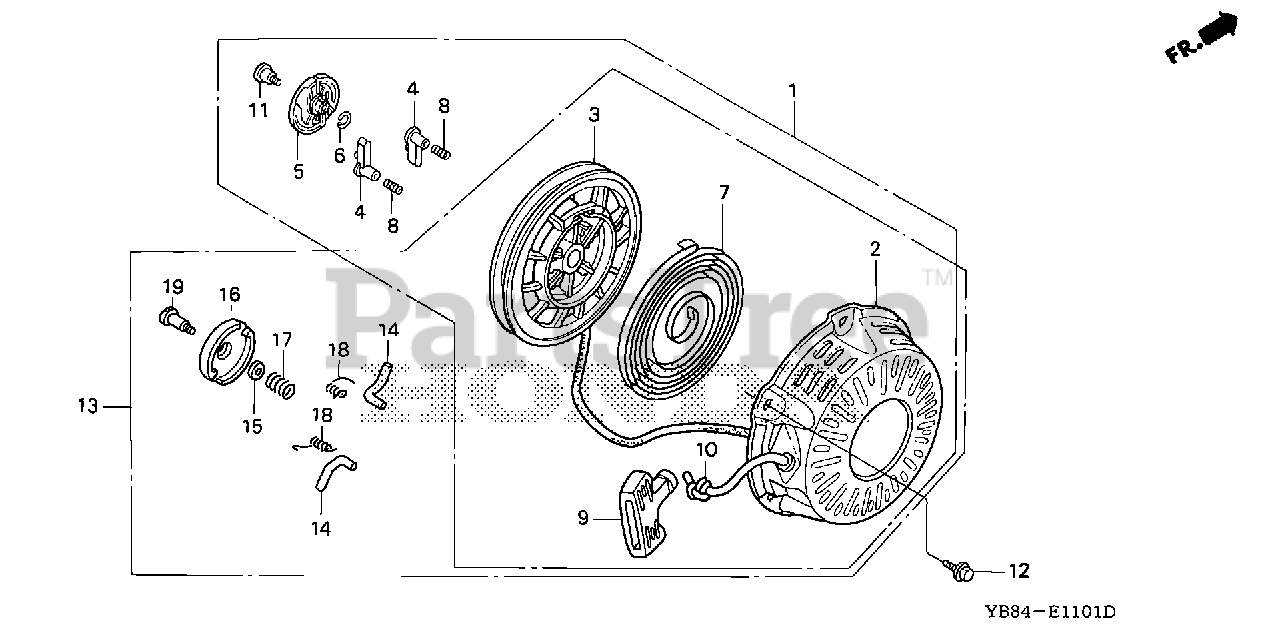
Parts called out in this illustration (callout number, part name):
1	STARTER ASSY., RECOIL *R280* (POWER RED)
2	CASE, RECOIL STARTER *R280* (POWER RED)
3	REEL, RECOIL STARTER (NATURAL)
3	REEL, RECOIL STARTER (BLACK)
4	RATCHET, STARTER
5	GUIDE, RATCHET
6	SPRING, FRICTION
7	SPRING, RECOIL STARTER
8	SPRING, RETURN
9	GRIP, STARTER
9	KNOB, RECOIL SRARTER
10	ROPE, RECOIL STARTER
11	SCREW, SETTING
12	BOLT, FLANGE (6X10)
13	STARTER ASSY., RECOIL *R280* (POWER RED)
14	RATCHET, STARTER
15	PLATE, FRICTION
16	GUIDE, RATCHET
17	SPRING, FRICTION
18	SPRING, RETURN
19	SCREW, SETTING
